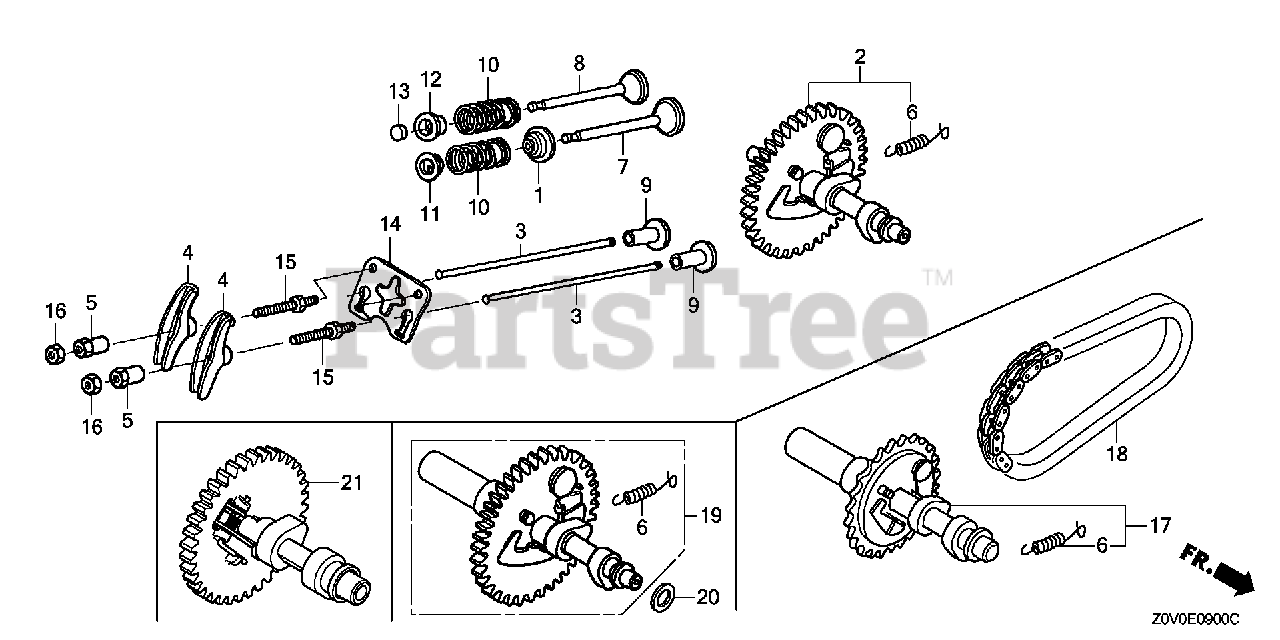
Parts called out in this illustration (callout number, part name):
1	SEAL, VALVE STEM
2	CAMSHAFT ASSY.
3	ROD, PUSH
4	ARM, VALVE ROCKER
5	PIVOT, ROCKER ARM
6	SPRING, WEIGHT RETURN
7	VALVE, IN.
8	VALVE, EX.
9	LIFTER, VALVE
10	SPRING, VALVE
11	RETAINER, IN. VALVE SPRING
11	RETAINER, VALVE SPRING (EXHAUST SIDE)
12	RETAINER, IN. VALVE SPRING
12	RETAINER, VALVE SPRING (EXHAUST SIDE)
13	ROTATOR, VALVE
14	PLATE, PUSH ROD GUIDE
15	BOLT, PIVOT (8MM)
16	NUT, PIVOT ADJ.
